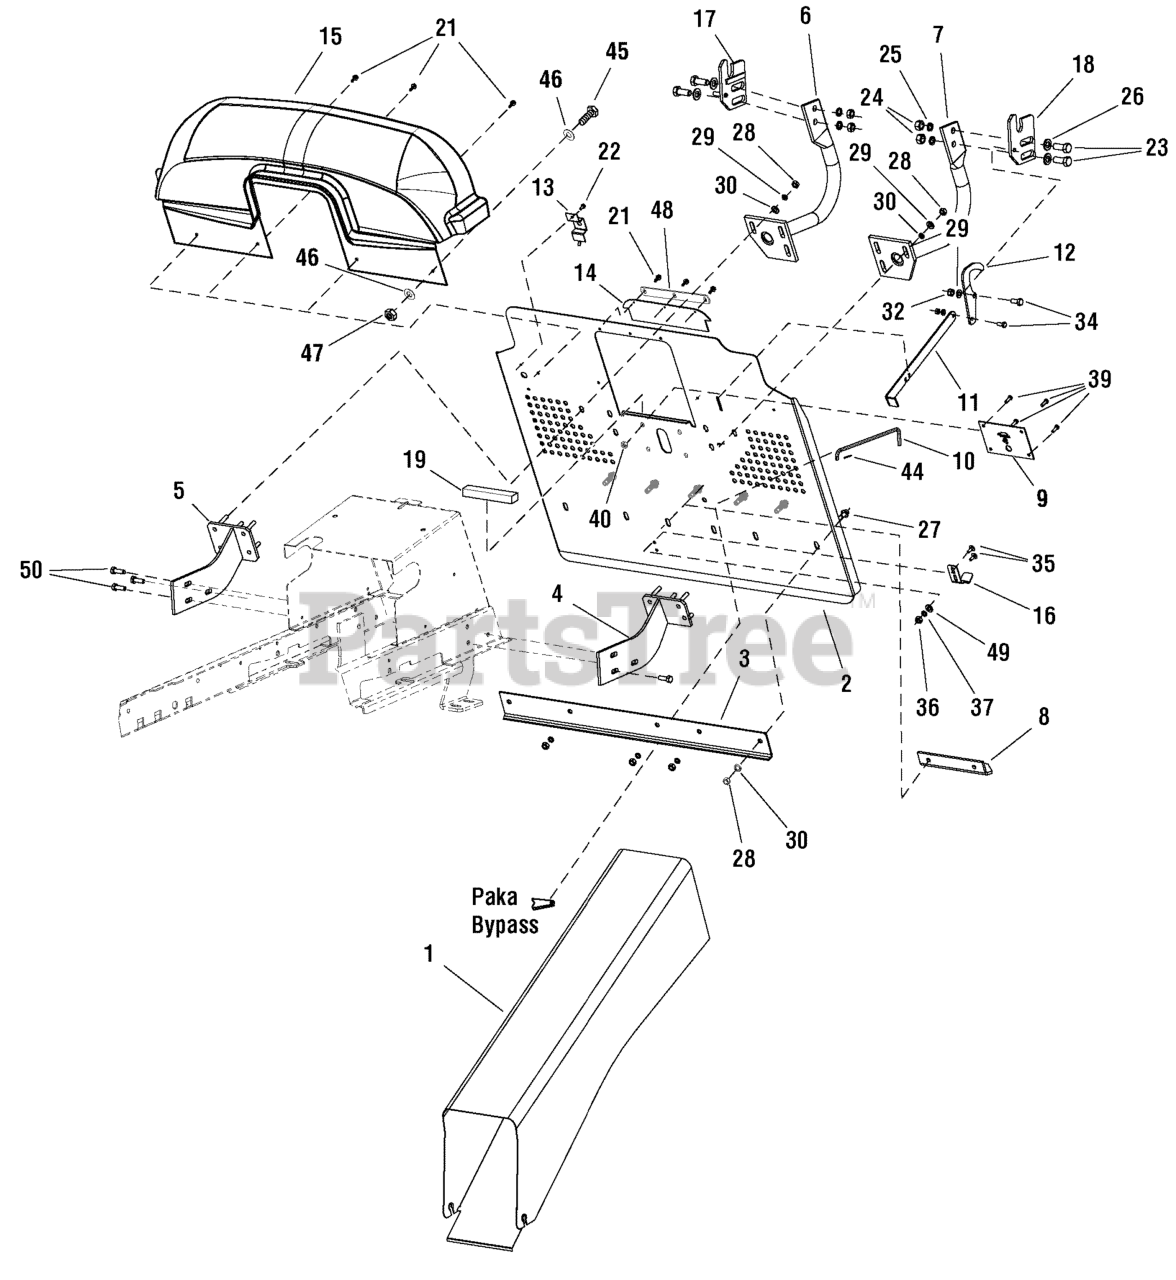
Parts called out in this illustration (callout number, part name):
2	BACKPLATE
4	HOLDER, Back Plate, L.H.
5	HOLDER, Back Plate, R.H.
6	HOLDER, Collector, R.H.
7	HOLDER, Collector, L.H.
9	SWITCH, Full Collector
10	TIE ROD, Bypass
11	TIE ROD, Latch
13	COVER, Switch
14	PAD, Rubber
15	TRANSITION PART
16	SPRING, Collector Lock
17	HOLDER, Adjustable, R.H.
18	HOLDER, Adjustable, L.H.
19	RUBBER EDGE
21	CAPSCREW, Self Tap, 5,5 x 19
22	CAPSCREW, Self Tap, 4.2 x 9.5
23	BOLT, M12 x 30
24	NUT, M12
25	WASHER, 13
26	WASHER, 12
27	BOLT, M8 x 25 DIN 6921 8.8
28	NUT, M8
28	NUT, Flange Lock, M8
29	WASHER, 8.4
30	WASHER, 8
34	CAPSCREW, M8 x 40
35	BOLT, M5 x 16
37	WASHER, 5.3
39	BOLT, M5 x 16
45	BOLT, M4 x 16
46	WASHER, 4.3
48	PAD, Steel
49	WASHER, 5.3
50	CAPSCREW, Hex Washer Head, Taptite, 5/16-18 x 5/8
